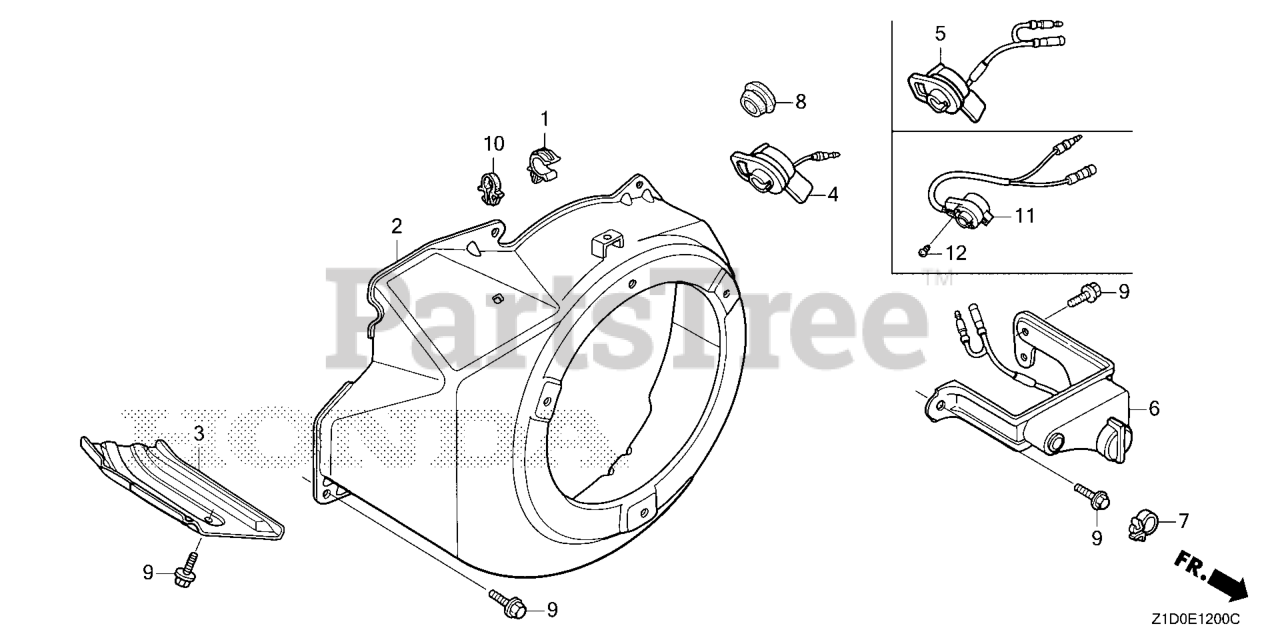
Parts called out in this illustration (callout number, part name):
1	CLIP, TUBE
2	COVER, FAN *NH1* (BLACK)
2	COVER, FAN *R280* (POWER RED)
9	BOLT, FLANGE (6X12) (CT200)
11	SWITCH ASSY., ENGINE STOP
12	SCREW, TAPPING (3X6) (PO)
